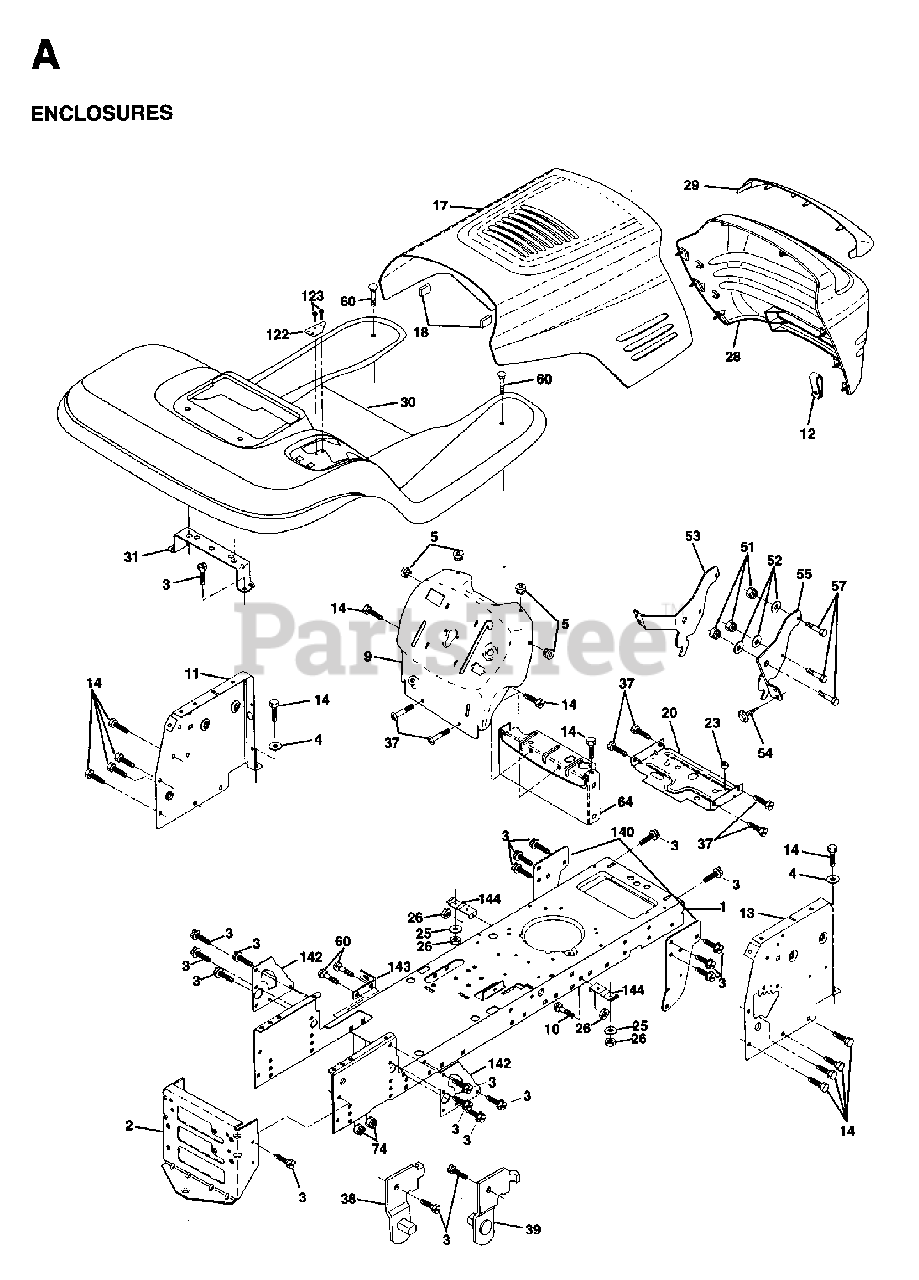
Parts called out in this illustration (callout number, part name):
1	CHASSIS WELDMENT
2	STRETCH DRAWBAR
3	SCREW
5	BUMPER.RUBBER.HOOD
10	BOLT D
11	PANEL PNT DASH LH
13	PANEL DASH RH
20	PLATE MTG
23	GROMMET T
25	WASHER
26	NUT
38	BRACKET LH PIVOT
39	BRACKET RH PIVOT
51	LOCKNUT
64	DASH LOWER
74	LOCKNUT
122	BRACKET SHIFT STLT
140	BRACKET CHASSIS FRONT
142	PLATE REINFORCEMENT
143	BRACKET, SWAY BAR
144	BRACKET FOOTREST
S7	BOLT
